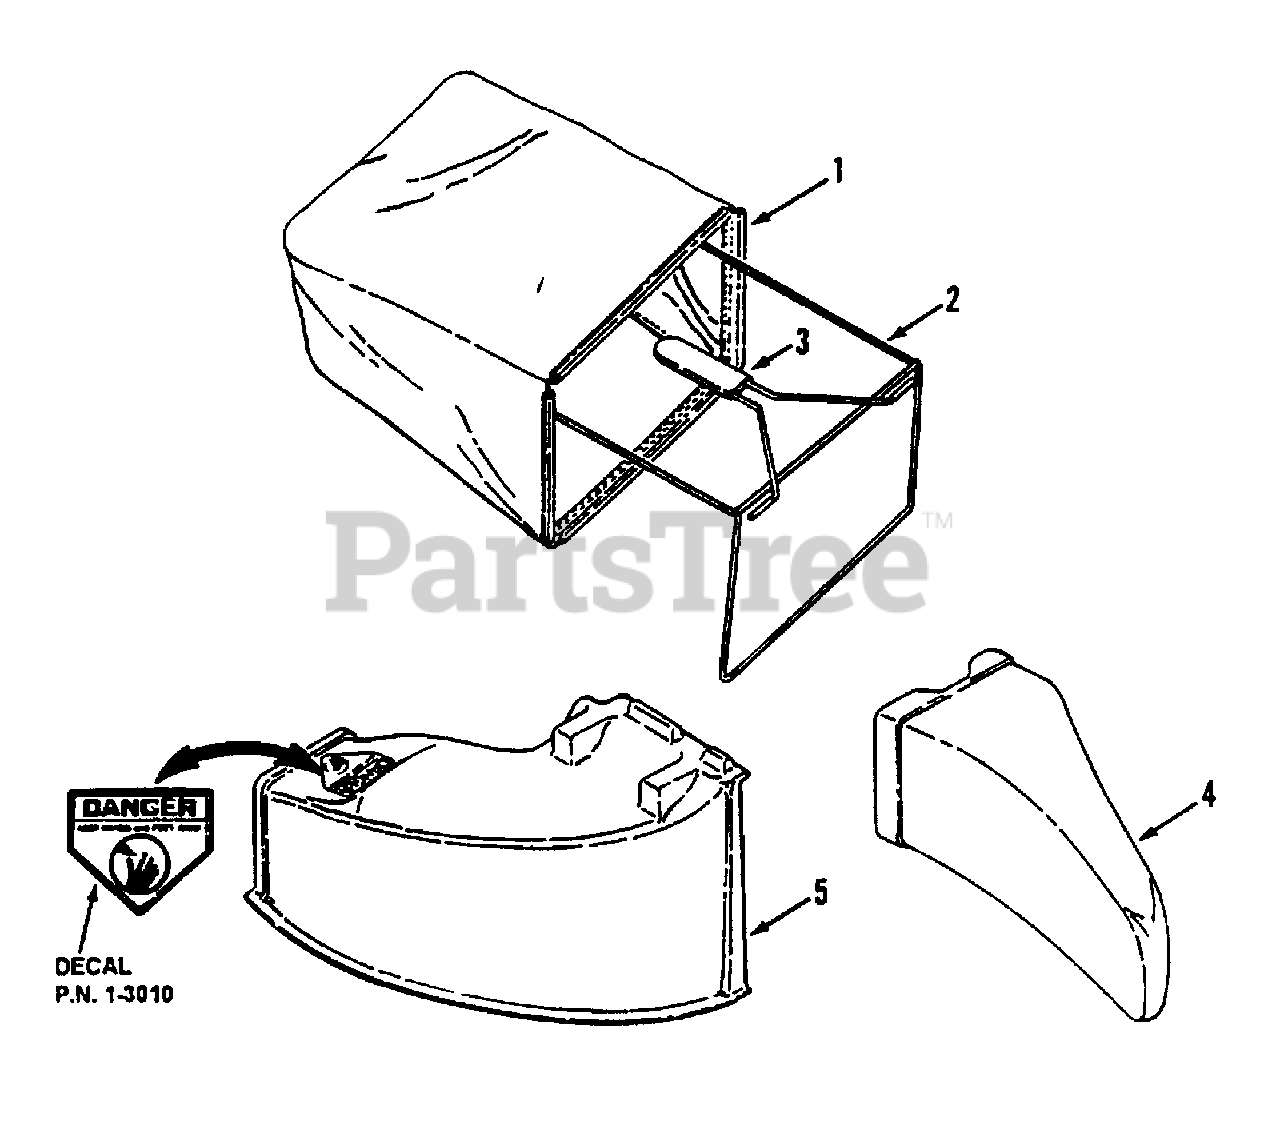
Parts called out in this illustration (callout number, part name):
1	GRASS BAG, Snapper Cast Aluminum Series
2	ASSEMBLY, Catcher Frame
3	GRIP, Catcher Frame
4	PLUG, Mulching
5	CHUTE, Side Discharge
